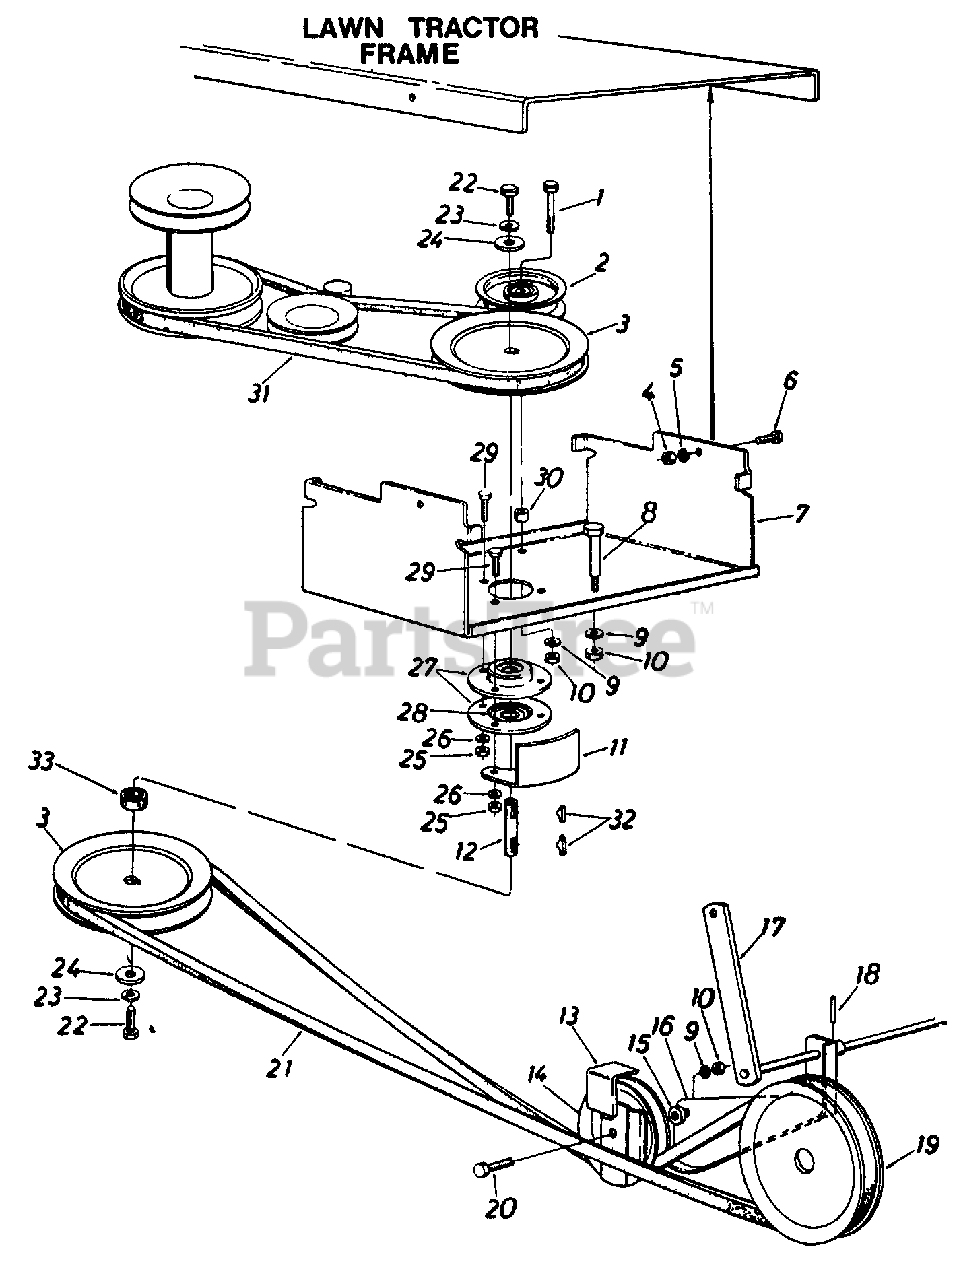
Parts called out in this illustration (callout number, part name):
1	Hex Bolt 3/8-16 x 2.00" Lg.*
2	Fl.-ldler w/ Flanges 3-3/4" O.D.
3	5/8" "V"-Pulley .790" I.D. x .650" O.D.
4	Hex Nut 3/8-24 Thd.*
5	L.-Wash. 3/8" I.D. Heavy Duty
6	Hex Bolt 3/8-24 x .88" Lg.*
7	Carriage Bracket
8	Shoulder Bolt .498" Dia. x 1.64
9	L.-Wash. 3/8" I.D.*
10	Hex Nut 3/8-16 Thd.*
11	Belt Guard
12	Shaft.787" Dia. x 2.56" Lg.
13	Belt Separator Plate
14	Fl.-ldler w/ Flanges 3.25" O.D.
15	Fl.-Wash. .406" I.D. x 1.25" O.D. x .164
18	Spring Pin Roll 3/16" Dia. x 1.50" Lg.
19	5/8" V-Pulley 1.50" I.D. x 6.50" O.D.
20	Hex Bolt 3/8-16 x 1.75" Lg.*.
21	V-Belt 1/2" x 95.0" Lg.
22	Hex Bolt 5/16-18 x .88 " Lg. Spec.
23	L.-Wash. 5/16" I.D.*
24	Fl.-Wash. .344" I.D. x 1.125" O.D. x .125
25	Hex Nut 5/16-18 Thd.*
26	L.-Wash. 5/16" I.D.*
27	Bearing Housing 1.85" I.D.
28	Ball Bearing.787" I.D. x 1.85" O.D.
29	Hex Sems Bolt 5/16-18 x .75"
30	Spacer
31	Belt 1/2" Wide x 52" Long
32	Hi-Pro Key 3/16" x 5/8"
33	Spacer-.80" I.D. x 1.0" O.D.
